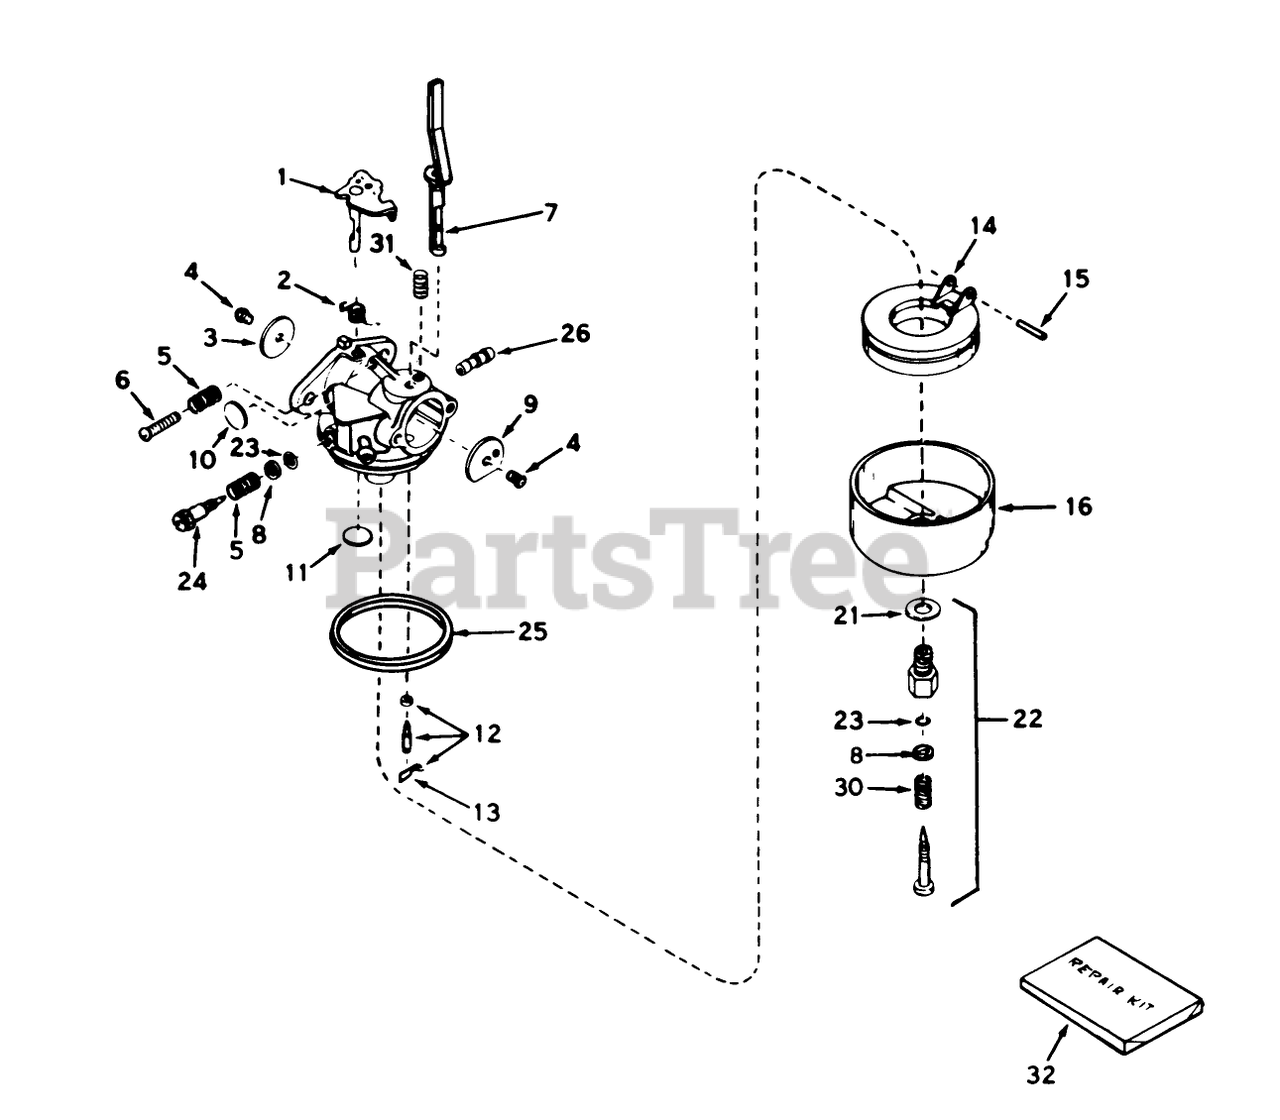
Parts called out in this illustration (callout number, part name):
1	Shaft/Lever-Throttle
2	Spring, Return
3	Shutter-Throttle
4	Screw-Shutter
5	Spring-Tension
6	Screw-Throttle Crack Screw / Idle Speed
7	Shaft Lever Assy., Choke
8	Washer
9	Shutter-choke
10	Plug-Welch, Idle Mixture Well
11	Plug-Welch, Atmospheric Vent
12	Inlet Needle, Seat Clip Assy. (Incl. No. 13)
13	Clip-Spring
14	Float
15	Shaft-Float
16	Bowl-Float (no drain)
21	Washer-Bowl Nut
22	Adjustment Screw Assy., Main (Incl. Nos. 5A, 21 23)
23	ORing
24	Screw, Idle Adj.
25	O Ring-Bowl, Float
26	Fuel Fitting
30	Spring
31	Spring-Positioning, Choke
32	Repair Kit (Incl. items marked *)
